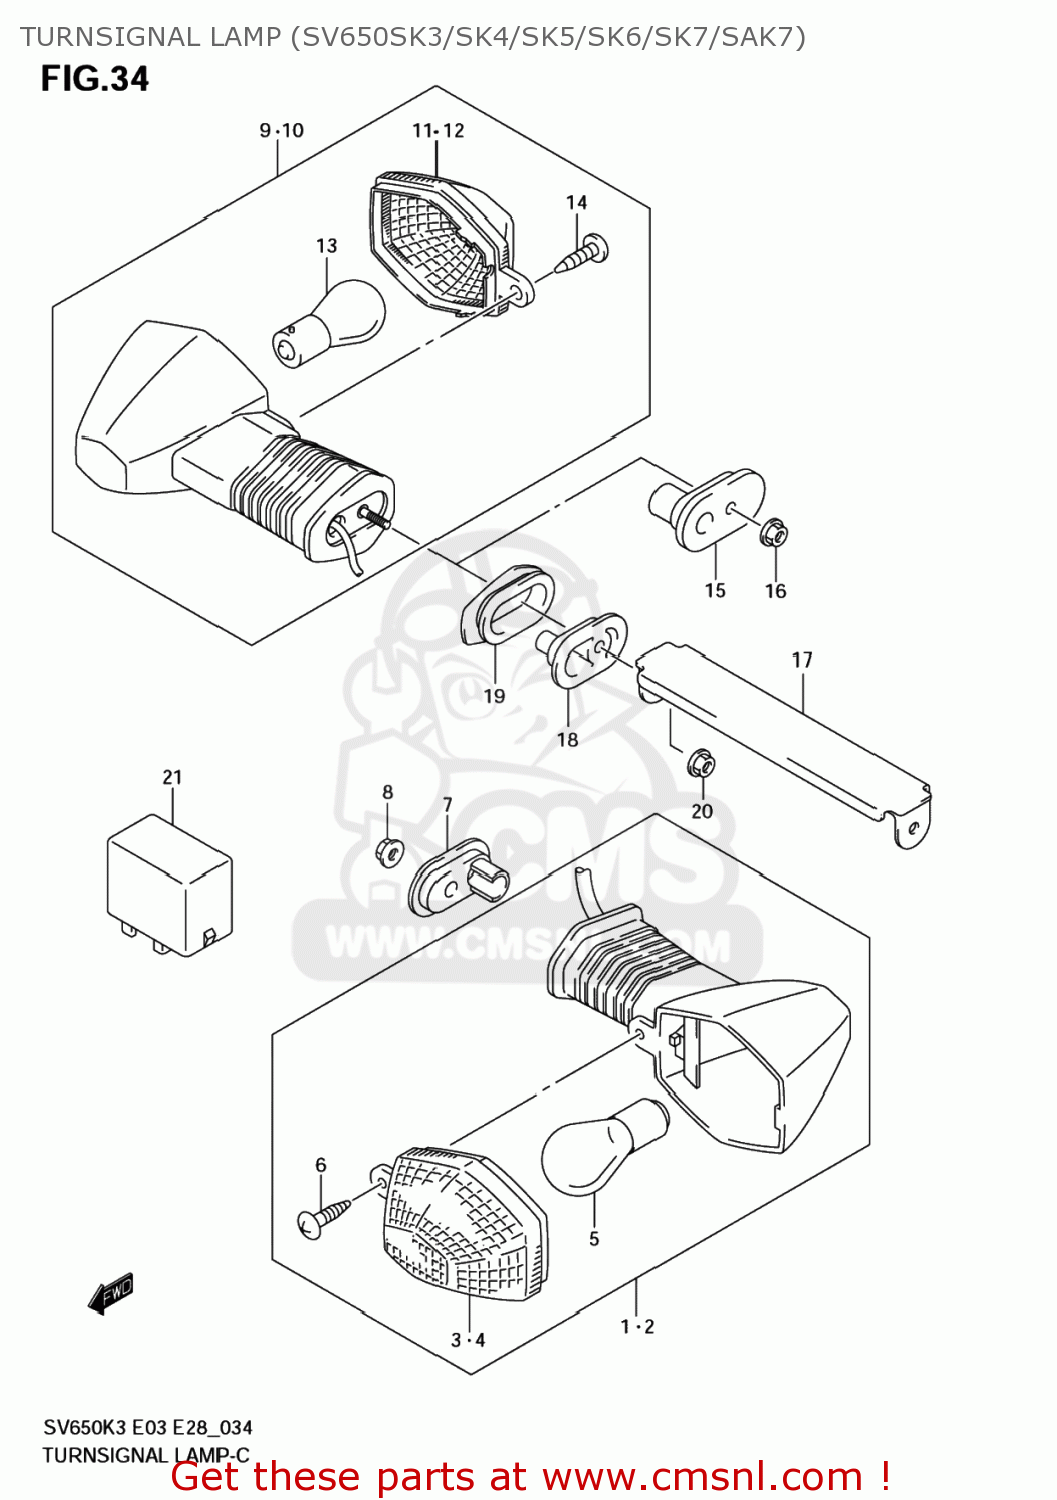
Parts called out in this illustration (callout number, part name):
1	LAMP ASSY,FR TURN,R
2	LAMP ASSY,FR TURN,L
3	LENS
4	LENS
5	BULB(12V21W)
6	SCREW
7	PLATE,TURNSIGNAL LAMP
8	NUT
9	LAMP ASSY,RR TURNSIGNAL,R
10	LAMP ASSY,RR TURNSIGNAL,L
11	LENS
12	LENS
13	BULB(12V21W)
14	SCREW
15	PLATE,TURNSIGNAL LAMP
16	NUT
17	BRACKET,RR TURNSIGNAL
18	PLATE,RR TURN SIGNAL
19	CUSHION,RR
20	NUT
21	RELAY ASSY,TURNSIGNAL LAMP
